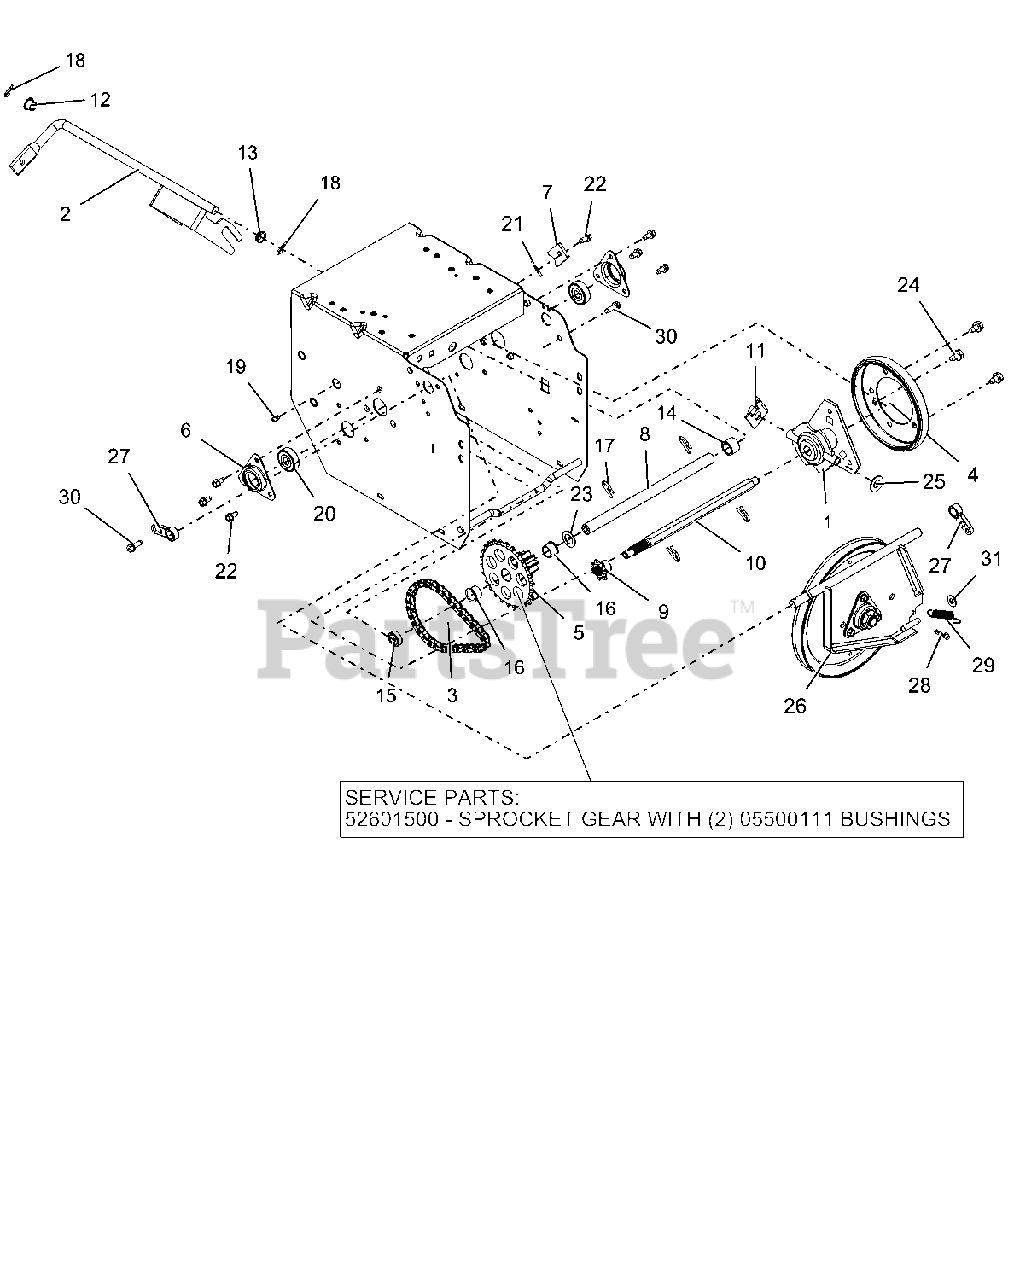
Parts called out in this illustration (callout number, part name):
1	CARRIER, DRIVE DISK
2	WELDMENT, SHIFT FORK
3	CHAIN - #41, 32 PITCHES
4	FRICTION, DISC
5	BSHG-FLG .625X.750X.500X.875
5	PINION & SPROCKET
5	PINION & SPROCKET W/BUSHINGS
6	FLANGE, BEARING
7	TAB, ANTI ROTATION
8	SHAFT, PINION
9	SPROCKET, PINION 7T W/SPLINE
10	SHAFT, HEX W/SPLINE
11	BRACKET, FORMED - SHIFT FORK
12	BUSHING, POLYLINER-.50 SPLIT
13	BUSHING, POLYLINER-.50 SNAPIN
14	SPACER, .635X.880X.611
15	BSHG-SLV, .635X.880X.305
16	BSHG-FLG .625X.750X.500X.875
17	PIN, SPRING CLIP
18	CLIP, SPRING
19	ZERK,FITTING .25X.125 DRIVE IN
20	BRG-BALL .437X1.375X.437
21	@PIN-GRV .125X1.00 TP E ALLOY
22	SCR-TAP .25-20X.50 HWH TR YWZ
23	WSHR-FL-STL .630X1.005X.062 YZ
24	@SCR-TAP .31-18X.50 HWH TR YWZ
25	WSHR-FL-STL .505X1.00X.062YWZC
26	PLATE, SWING - ASSEMBLY
27	SUPPORT BUSHING, SWING GATE
28	PIN-HAIR INT .08X.18X1.18 YWZC
29	SPRING, EXT. .043X.438X1.64
30	SCR-TAP-PM .25-20X.75 TR YWZ
31	@WSHR-FL-STL.344X.688X.065YWZC
